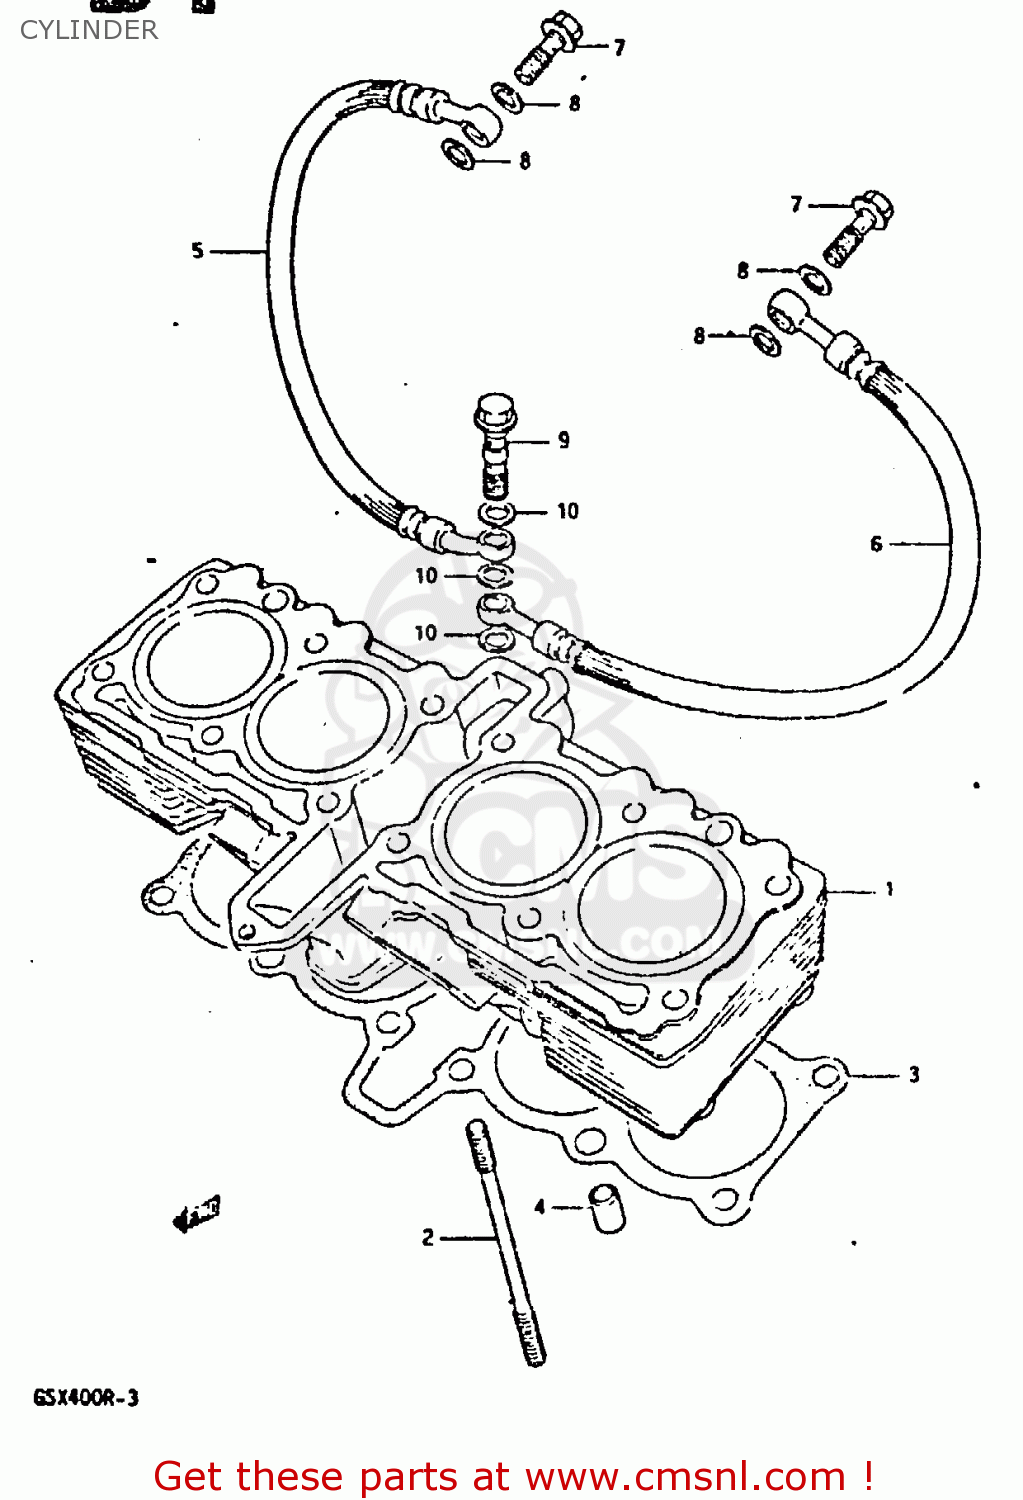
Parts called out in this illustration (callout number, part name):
1	CYLINDER
2	BOLT,STUD(8X120)
3	GASKET,CYLINDER
4	PIN
5	RH HOSE
6	OLIELEIDING. L.
7	BOLT UNION
8	GASKET 8.2X14X1 (NAS)
9	BOLT UNION
10	WASHER(10X15X1.5)
